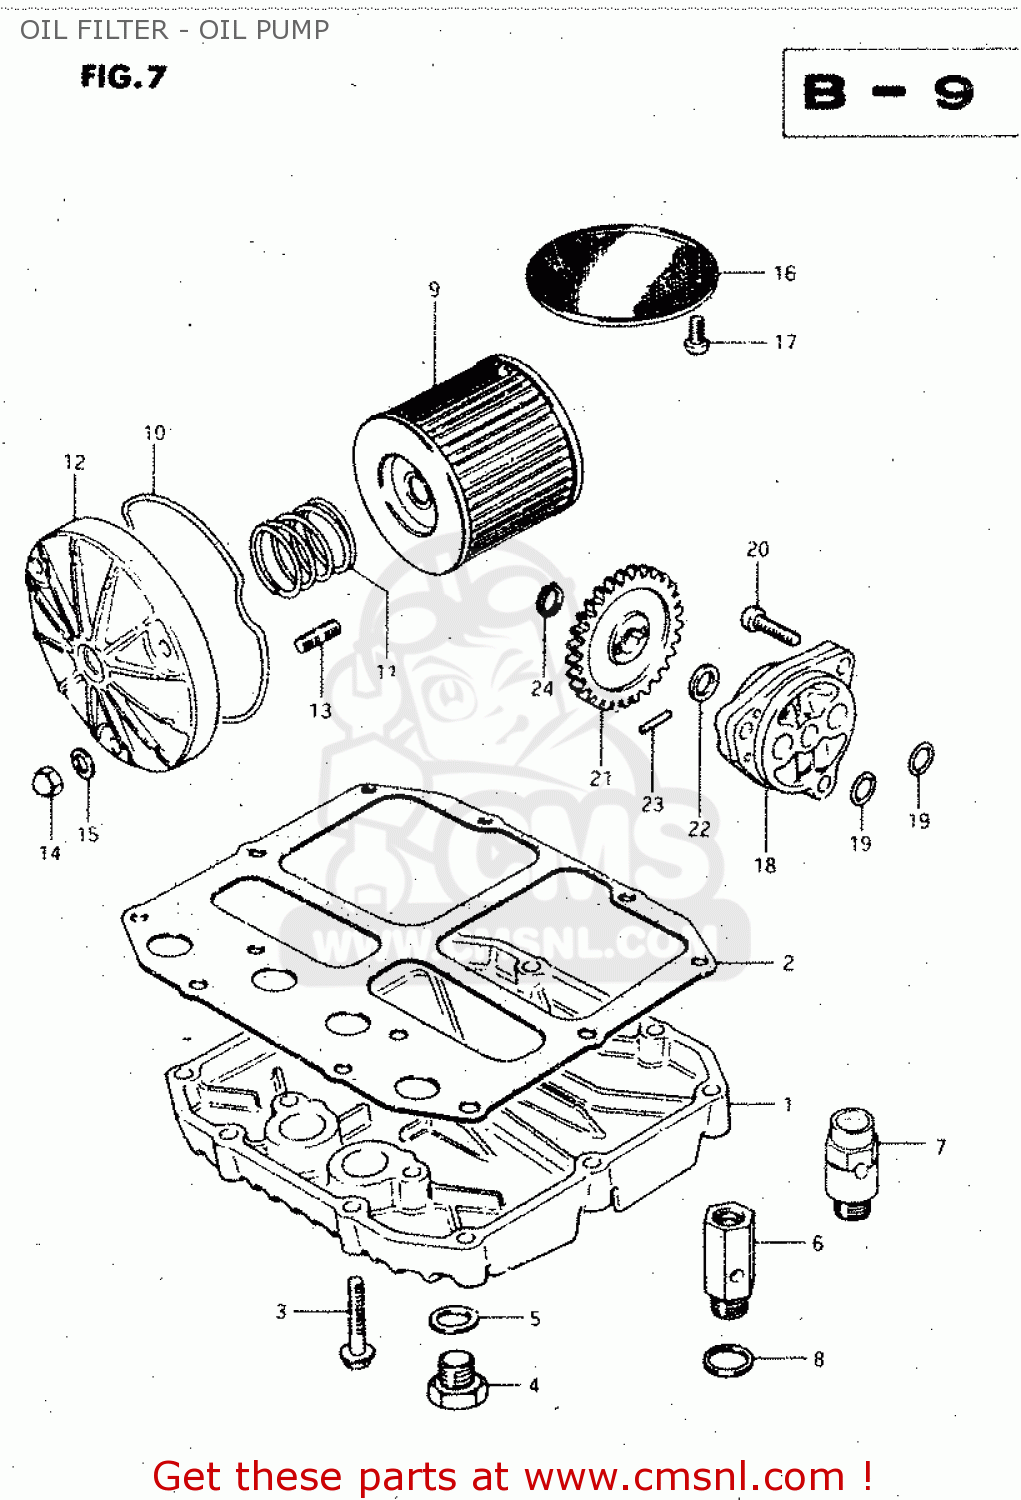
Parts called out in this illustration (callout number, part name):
1	PAN,OIL
2	GASKET,OIL PAN (MCA)
3	BOLT
4	PLUG
5	GASKET(14X19.2X2) (NAS)
6	REGULATOR ASSEMBLY,ENGINE
7	REGULATOR ASSEMBLY,ENGINE
8	WASHER
9	FILTER ASSY,ENGINE OIL
10	O RING,OIL FILTER CHAMBER CAP
11	SPRING
12	CAP,ENGINE OIL FILTER
13	STUD 6X20
14	NUT
15	WASHER
16	STRAINER,ENGINE OIL
17	SCREW 6X12
18	PUMP ASSY,ENGINE OIL
19	O RING(D:1.9,ID:13)
20	SCREW
21	GEAR,OIL PUMP DRIVEN
22	SHIM
23	PIN(4X15.8)
24	CIRCLIP
